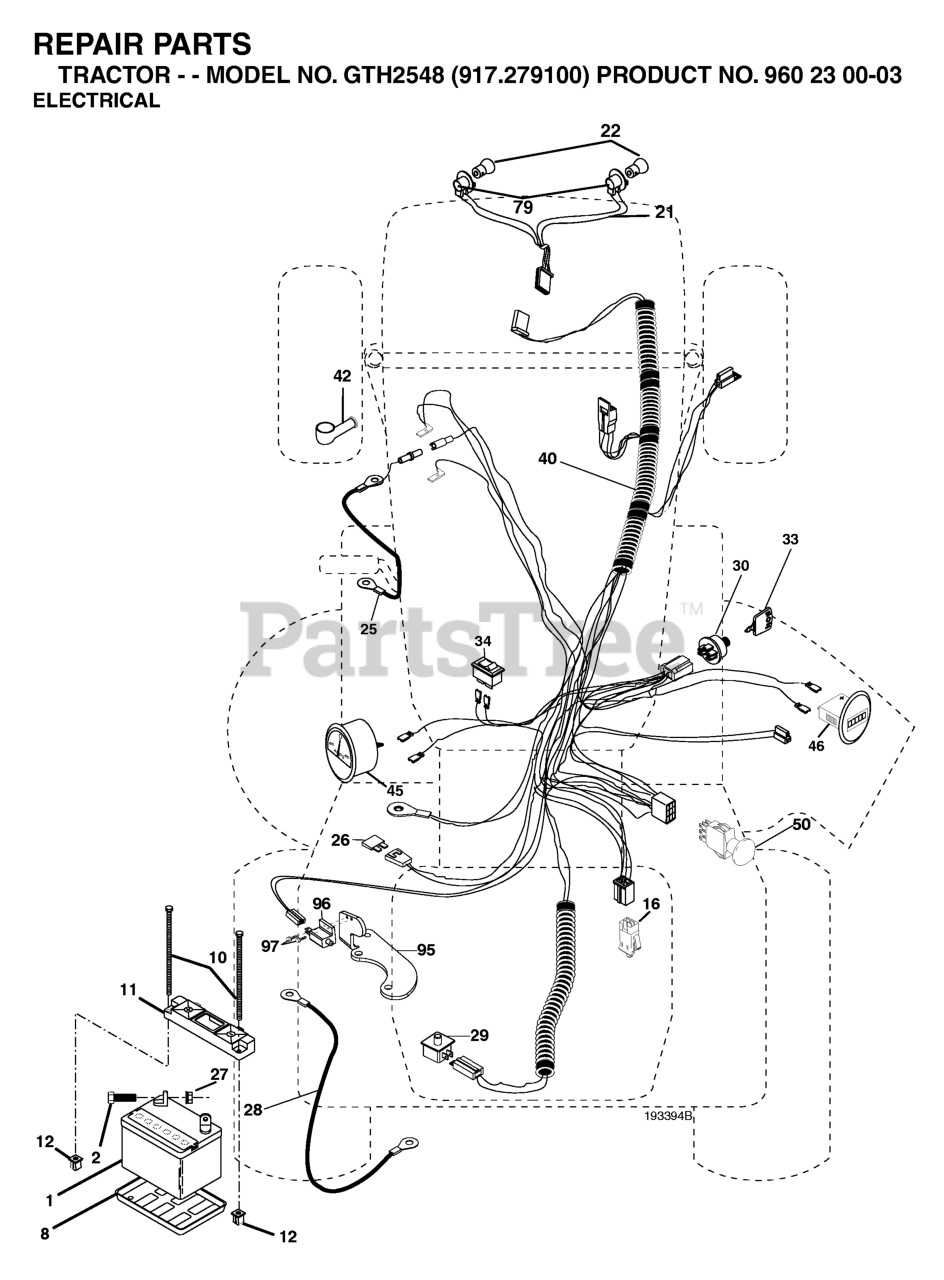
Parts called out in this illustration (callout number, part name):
1	BATTERY 12V .35 AMP
2	BOLT.HEX.1/4.X.3/4.DICHROMATE
8	BATTERY TRAY T
10	BOLT 1/4-20 X 7.5
11	BATTERY HOLDDOWN FRONT MOUNT
12	NUT, PUSH NYLON 1/4" BATTERY
16	SWITCH INTERLOOK PUSH-IN
21	HARNESS.W/LIGHT SOCKET
27	NUT
28	CABLE, GROUND
29	SWITCH.SEAT.DP W/RAMPS
30	SWITCH.IGN.DELTA.W.LGH.ROS
33	KEY MLD GEN DELTA
40	HARNESS. IGN.VGT.RHD
42	COVER.TERMINAL.RED
45	RP AMMETER.ROUND.SILVER.DELTA
46	RP HOURMETER SNAP-IN
50	RP.PTO.SWITCH.8 TERMINAL.BLACK
79	BULB HOLDER ASM.
92	HARNESS.PIGTAIL.REVERSE.SWITCH
93	SCREW.PLASTITE
94	MODULE.REVERSE.ROS
